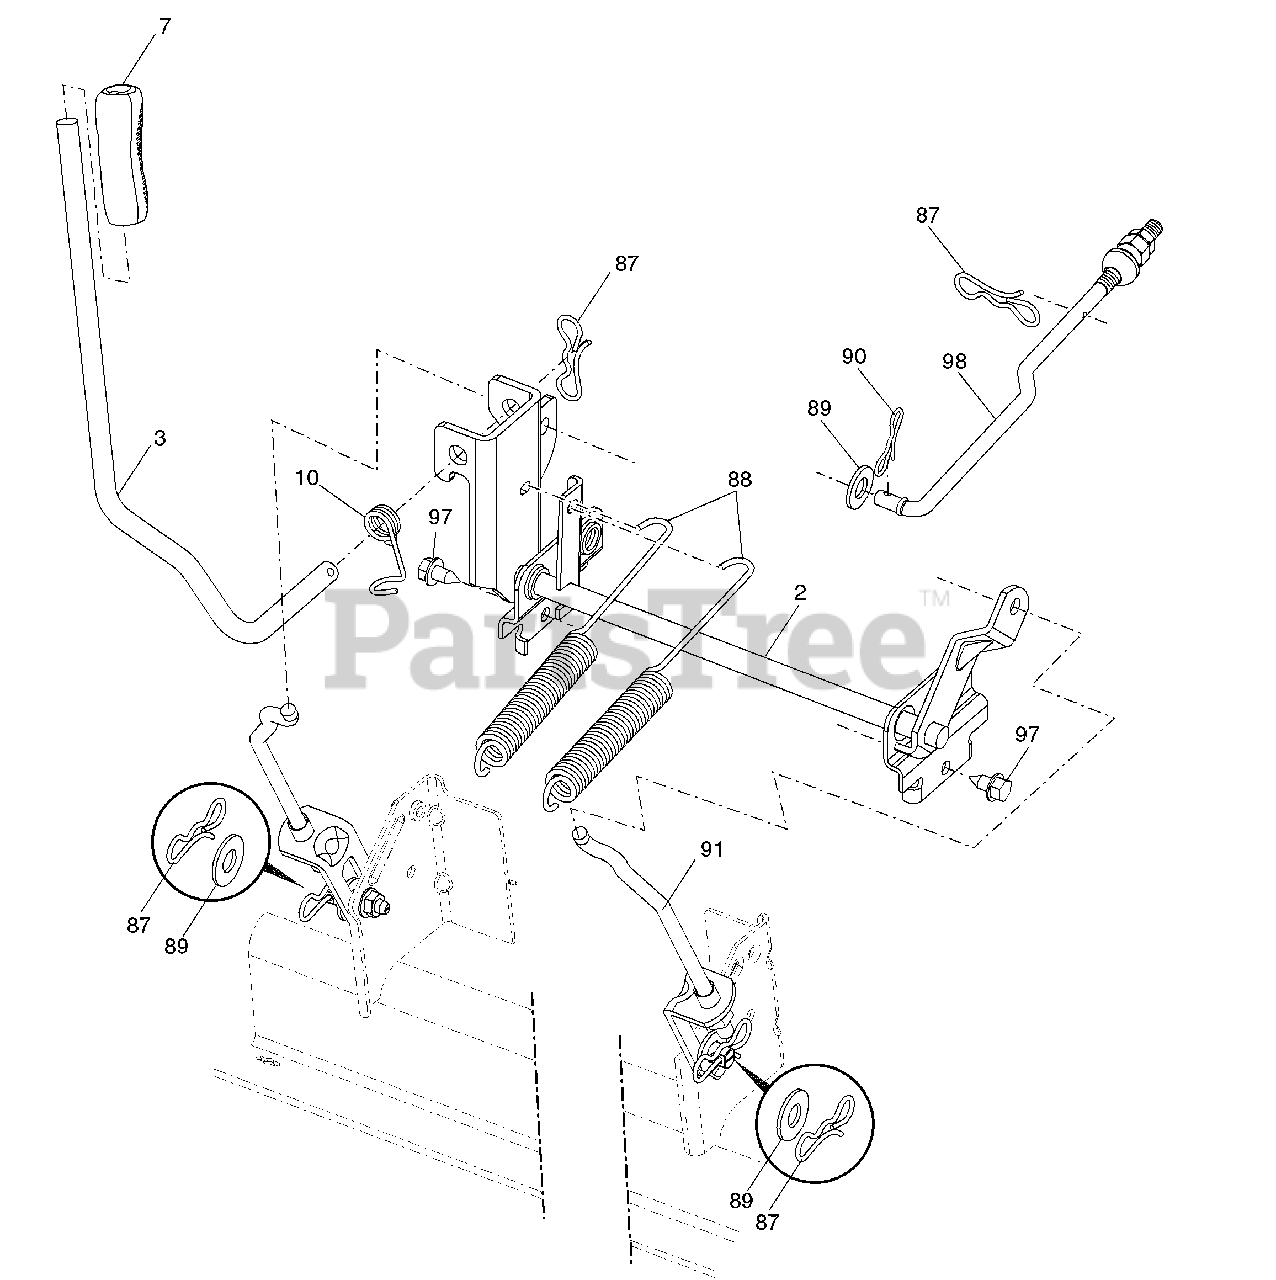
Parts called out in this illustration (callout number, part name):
2	Shaft Asm., Lift
3	Lever Asm., Lift Rh
7	Grip, Lever
10	Spring Torsion
87	Pin Cotter 7/16 Bow Tie Lock
88	Spring Lift Assist
89	Washer Clear Zinc
90	Pin Cotter 5/16 Bow Tie Lock
91	Link Lift Susp Mower Rear
97	Screw 3/8-16 x .75 Smgml Tap/R.Z
98	Link Lift Susp. Front Mower
